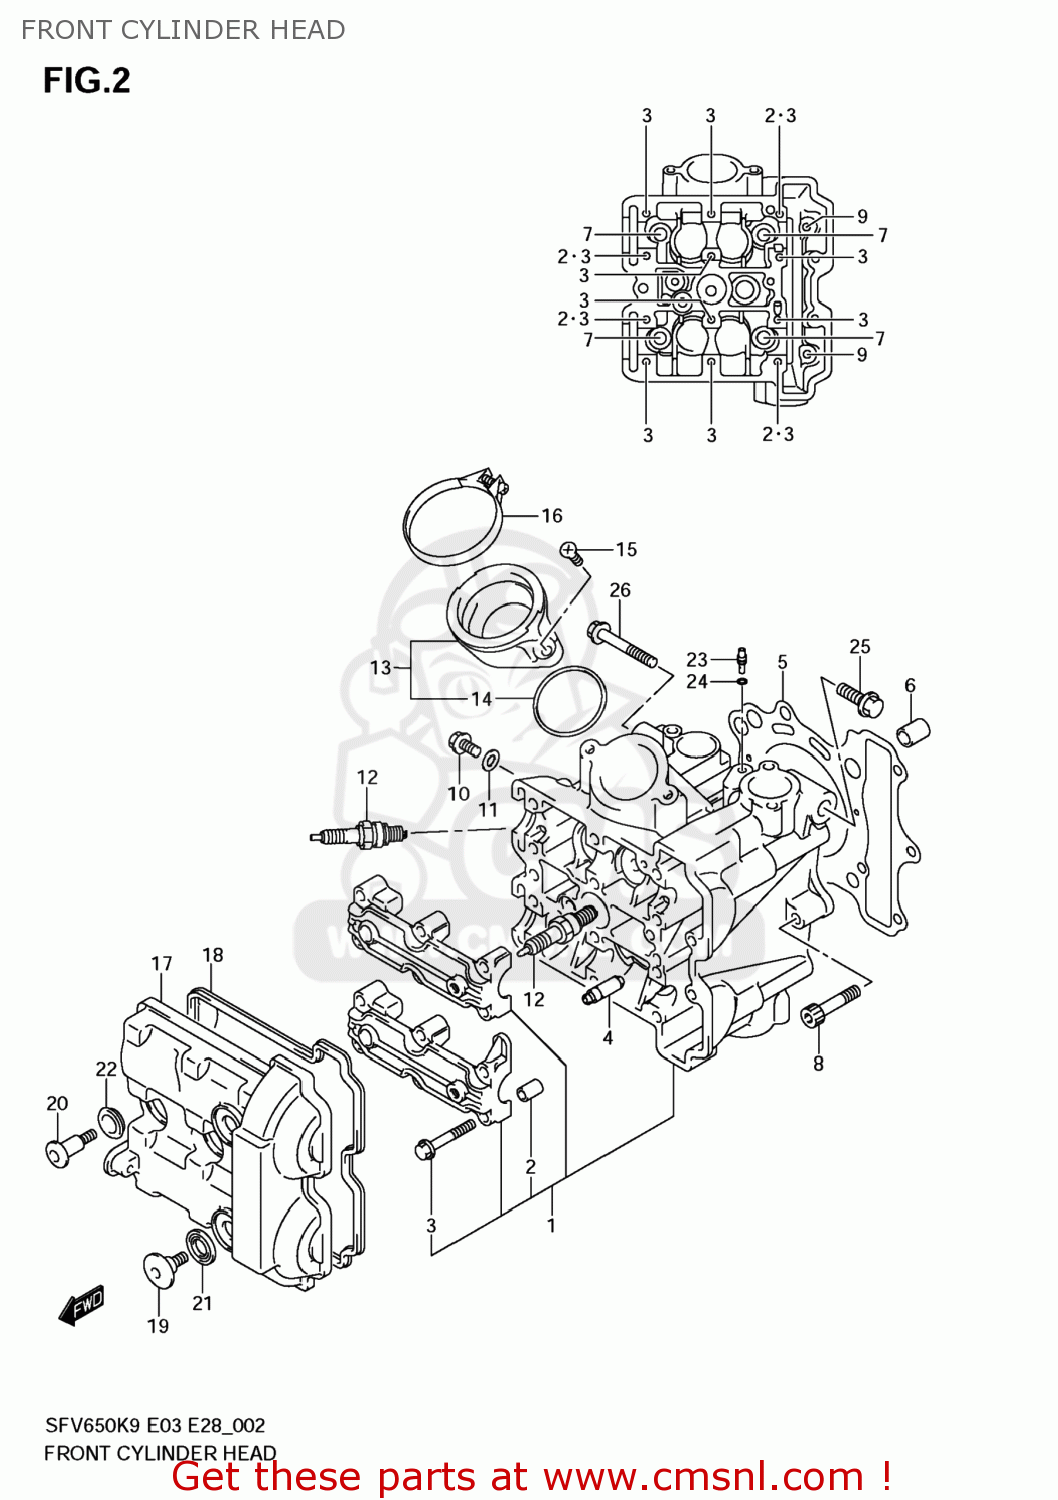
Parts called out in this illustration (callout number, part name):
1	HEAD ASSY,CYLINDER FR
2	PIN(6.2X8X11)
3	BOLT(6X39)
4	GUIDE,VALVE
5	GASKET,CYLINDER HEAD (NAS)
6	PIN
7	BOLT,CYLINDER HEAD(L:160)
8	BOLT
9	BOLT(6X70)
10	BOLT
11	GASKET(5.8X13X1.2) (NAS)
12	PLUG,SPARK(IU24D)
13	PIPE ASSY,INTAKE FR
14	O RING(D:2.4,ID:47X42)
15	SCREW
16	CLAMP
17	COVER,CYLINDER HEAD FR
18	GASKET,CYLINDER HEAD COVER (NAS)
19	BOLT(7X17.5)
20	BOLT(7X31)
21	WASHER,CYL HEAD COVER
22	CUSHION,HEAD COVER BOLT
23	JET(8)
24	O RING(D:1.2,ID:4)
25	BOLT(10X25)
26	BOLT
